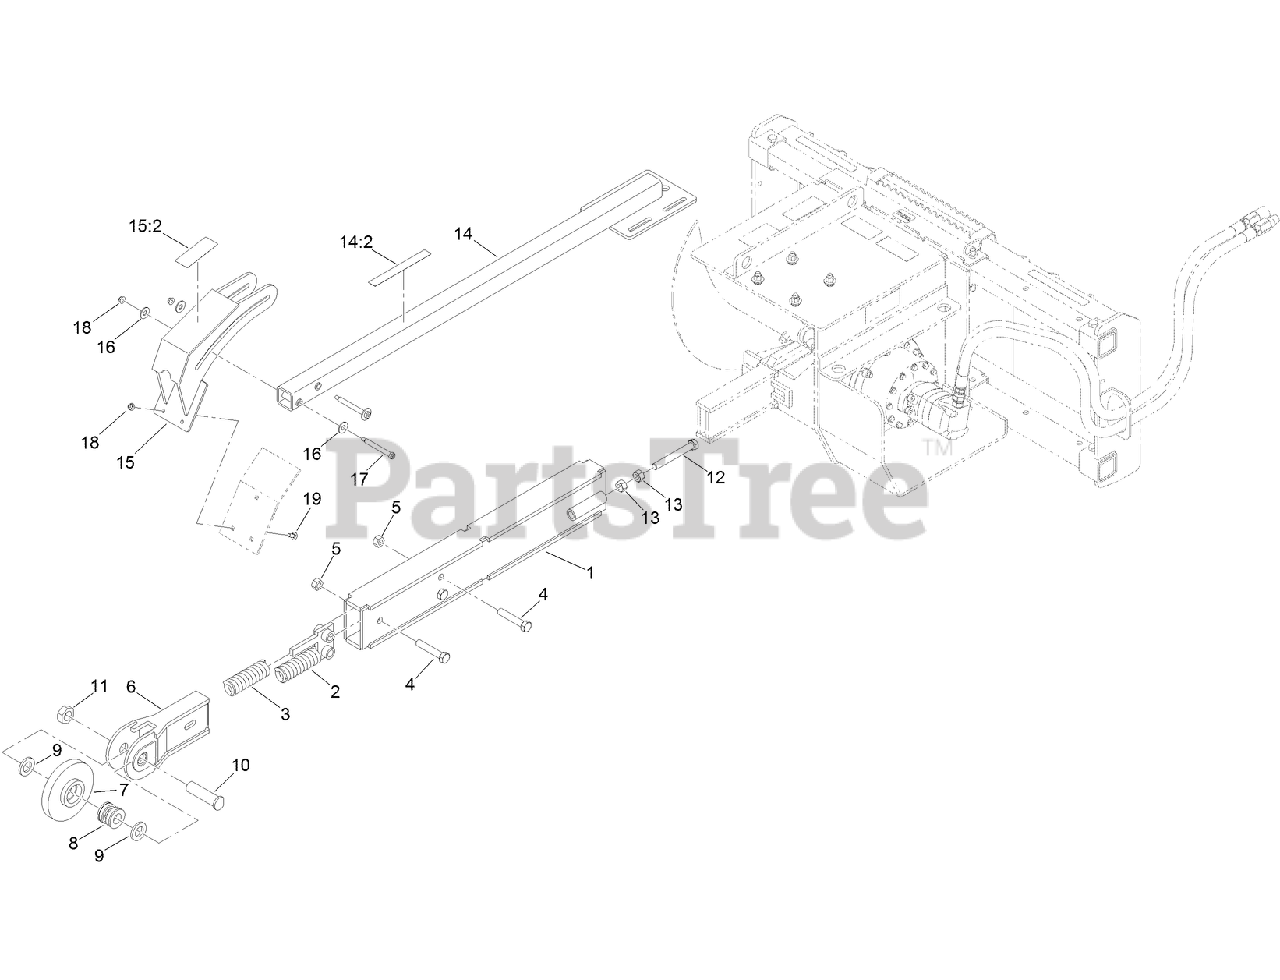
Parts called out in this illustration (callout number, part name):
1	ARM-BOOM
2	GUIDE-SPRING, TRENCHER
3	SPRING-COMPRESSION
4	SCREW-HH
5	NUT-LOCK
6	MOUNT-WHEEL, IDLER
7	WHEEL-IDLER
8	BEARING
9	SPACER
10	SHAFT-IDLER
11	NUT-LOCK, NI
13	NUT-HEX
14	CRUMBER ARM ASM
14:2	DECAL-DANGER
15	CRUMBER ASM
15:2	DECAL-DANGER
16	WASHER-FLAT
18	NUT-HF, NI
19	SCREW-HH
